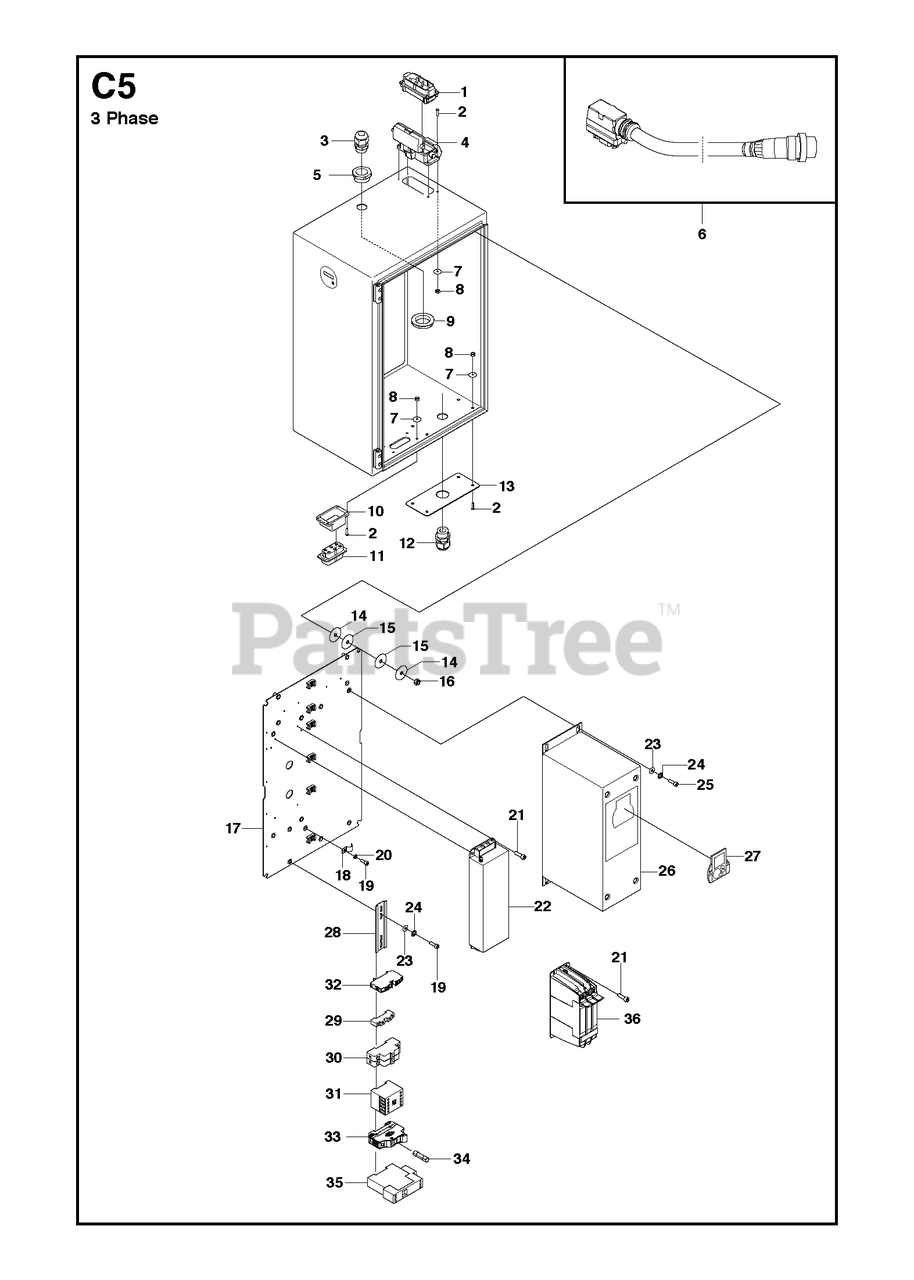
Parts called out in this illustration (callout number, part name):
2	SCREW CRPANM
8	HEXAGON LOCKING NUT
16	HEXAGON LOCKING NUT
